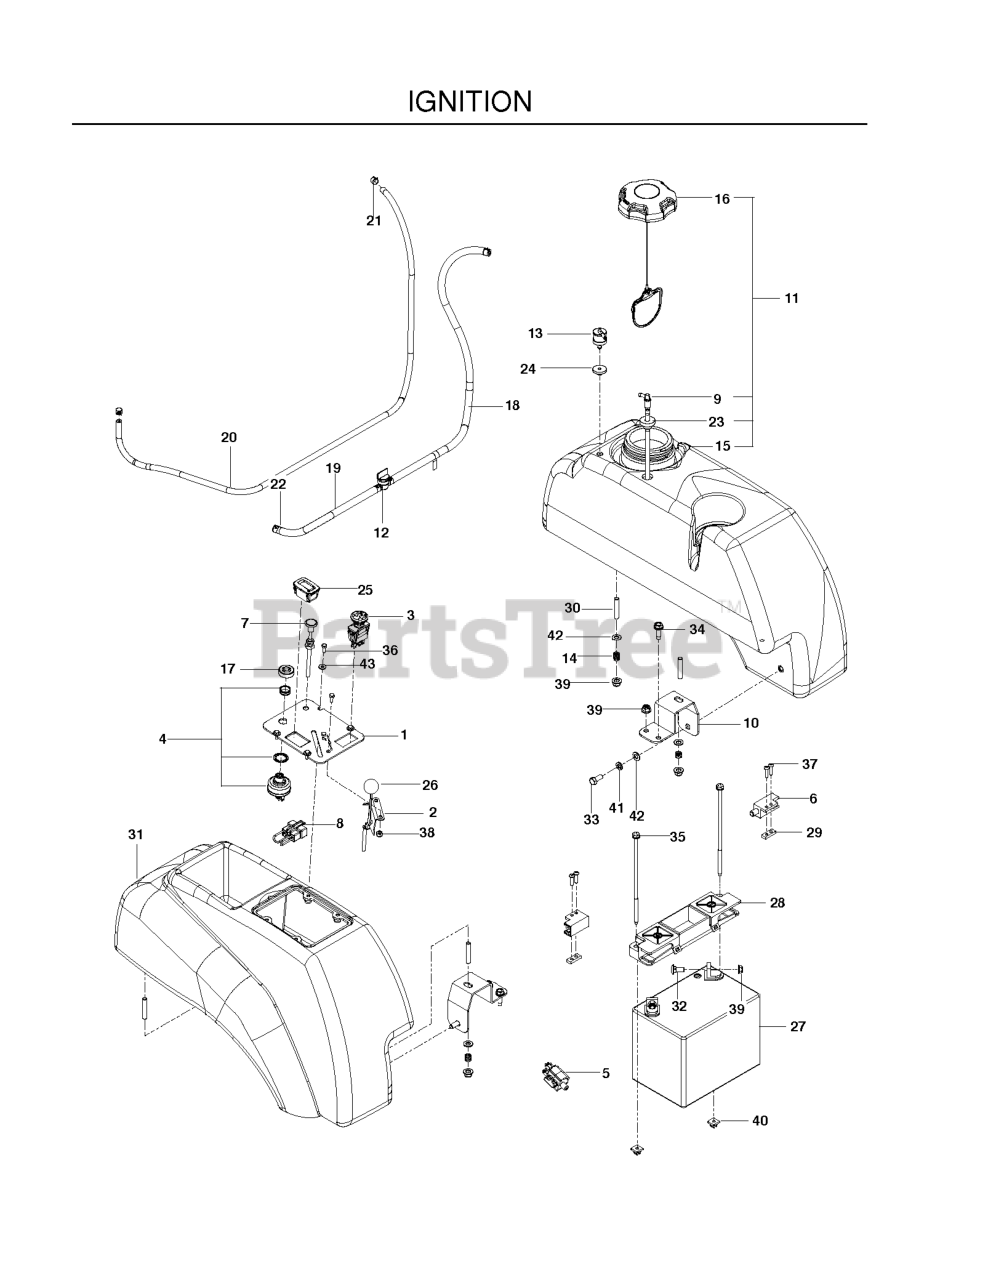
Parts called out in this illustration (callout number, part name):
1	PLATE.CONSOLE.BLACK
2	THROTTLE CABLE
3	SWITCH, PTO 10 AMP
4	SWITCH, IGNITION, INDAK
5	SWITCH, BRAKE 3P
6	SWITCH INTERLOCKT
7	CHOKE CABLE
8	PLUG, TIMER
9	FITTING, FUEL
10	SUPPORT, TANK, BLK
11	ASSEMBLY, LT TANK, EPA GRAY
12	FUEL VALVE
13	VALVE.FUEL.CHECK
15	TANK, FUEL, LT-EPA
16	CAP, FUEL
17	CAP IGNITION NUT
18	HOSE, FUEL .25 ID X 26"
19	GAS LINE 10"
20	HOSE, VAPOR 3/16 X 48"
21	CLAMP, HOSE
22	HOSE CLAMP
23	RUBBER GROMMET
24	GROMMET, CHECK VALVE
25	HOUR METER
26	KNOB.ROUND.BALL.BLACK
27	BATTERY, 12 V 330 AMP
28	BATTERY HOLD DOWN
29	TAPPED PLATE
30	STUD, 5/16C
31	FENDER CONSOLE
32	BOLT 5/16C X 3/4" CARRIAGE
33	HCS 5/16C X 3/4
34	RP BLT 5/16-18 X 1 THRD FORM D
35	BOLT - 1/4-20 X 7.5
36	HCS #10-24 X 1/2
37	SCR #10-24 X .75 SKT HD BLK
38	NUT 10-24 NYLOC
39	5/16-18 NYLOC FLANGE NUT
40	PUSH NUT-NYLON
41	WASHER.LOCK.HVY.HLCL.SPR.5/16
42	FLAT WASHER 5/16 SAE
43	WASHER #10
